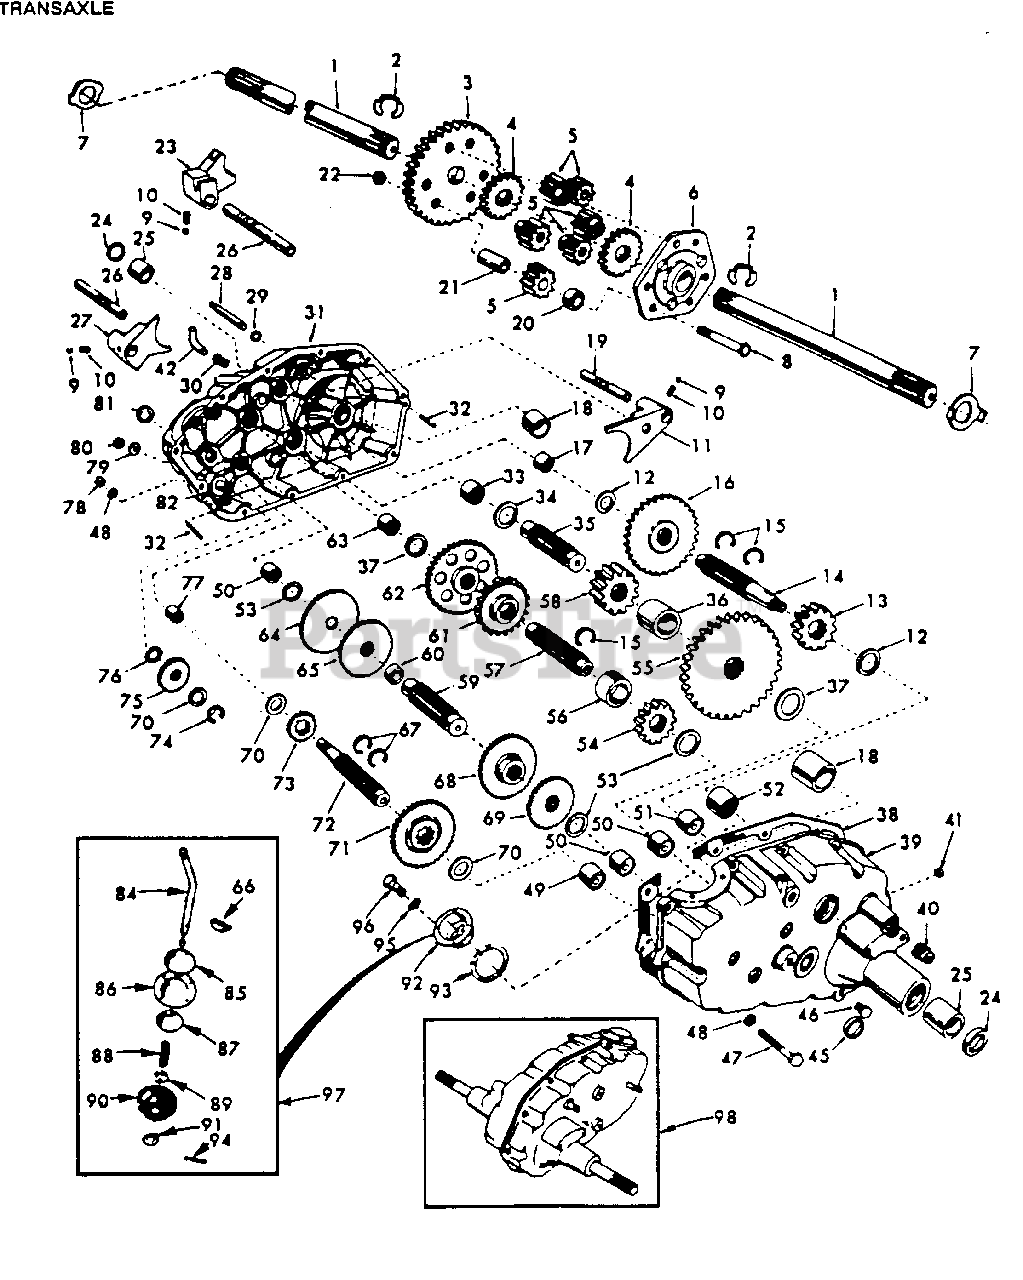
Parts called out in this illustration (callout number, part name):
1	Axle Shaft
2	Retaining Ring
3	Final Drive Gear
4	Differential Gear
5	Differential Pinion
6	Differential Carrier
7	Axle Thrust Washer
8	Hex Bolt 3/8-24 x 3-1/4 (1" Thread Length)
9	Steel Ball
10	Spring Shift Fork Detent
11	Shift Fork, High-Low Range
12	Thrust Bearing Race
13	4th Reduction Pinion
14	3rd Reduction Gear Shaft
15	Snap Ring, Crescent Type
16	High-Low Range Gears
17	Needle Bearing
18	Sintered Iron Bearing
19	Shift Fork Shaft, High-Low Range
20	Differential Pinion Spacer
21	Differential Pinion Bushing
22	Gripco Centerlock Nut 3/8-24
23	Shift Fork, L.H.
24	Oil Seal
25	Sintered Iron Bearing
26	Shift Fork Shaft
27	Shift Fork, R.H.
28	Shift Shaft, High-Low Range
30	Pressure Relief Valve
31	Gearcase, Rvs Idler Shaft & Bearings, R.H.
33	Needle Bearing
34	Thrust Bearing Race
35	4th Reduction Gear Shaft
36	4th Reduction Gear Spacer
37	Thrust Bearing Race
38	Gearcase Gasket
39	Gearcase & Bearings, L.H.
40	Pipe Plug 1/2-14 N.P.T.
41	Hex Bolt 5/16-18 UNC x 1-5/8 Grade 5
42	Elbow, Street, 90ø
46	Pipe Plug 1/4-18 N.P.T.
47	Hex Bolt 5/16-18 x 1-1/2 Grade 5
48	Washer, Lock, Extra Heavy 5/16
49	Needle Bearing
50	Needle Bearing
51	Needle Bearing
52	Needle Bearing
53	Thrust Bearing Race
54	3rd Reduction Pinion, Low
55	4th Reduction Gear
56	3rd Reduction Pinion Spacer
57	2nd Reduction Gear Shaft
58	Final Drive Pinion
59	1st Reduction Gear Shaft
60	1st Reduction Shaft Spacer
61	3rd Reduction Plnion Hlgh
62	2nd Reduction Gear
63	Needle Bearing
64	Low Speed Gear and 2nd Reduct??on Pinion Cluster
66	Key (Hi-Pro) 1/8 x 17/32
67	Snap Ring, Crescent Type
68	Intermediate Speed Gear
69	High Speed Gear
70	Thrust Bearing Race
71	Intermediate and High Speed Cluster Pinions
73	Low Speed Pinion
75	Reverse Idler Gear
76	Reverse Idler Thrust Washer
77	Needle Bearing
78	Hex Nut 5/16-18
79	Sealing Washer
80	Hex Jam Nut 7/16-20
81	Oil Seal
82	Reverse Idler Shaft
84	Gear Shift Lever, Bent
85	Gear Shift Cap
86	Gear Shift Ball Cover and Pin
87	Shift Lever Guide Ball, Keyed
89	Washer 15/32 x 15/16 x 16 Gauge
90	Shift Mechanism Seal
91	Washer 9/16 x 15/16 x 12 Gauge
92	Gear Shift Gate and Reinforcement
93	Shift Ball Cover Gasket
94	Cotter Pin 1/8 x 3/4
95	Washer, Lock 5/16
96	Hex Bolt 5/16 x 18 UNC x 7/8
97	Gear Shift Lever Assembly
98	Transaxle Assembly (Less Brake Drum and Shift Lever)
